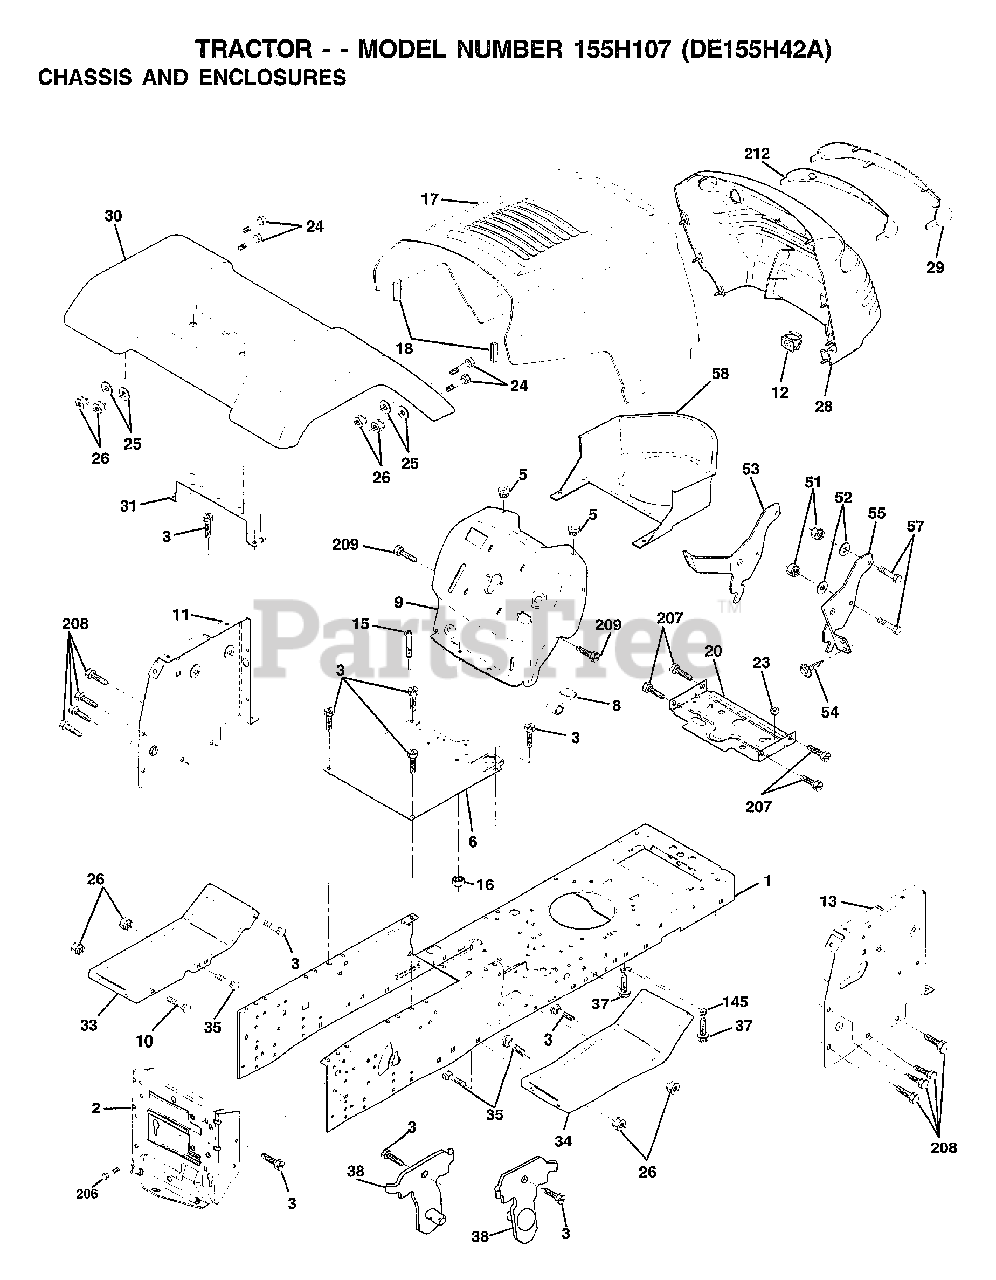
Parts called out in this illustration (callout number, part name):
2	DRAWBAR
3	SCREW
5	BUMPER-HOOD/DASH
6	SADDLE
8	CLIP.RETAINER
9	DASH
11	"PANEL-DASH,LH"
12	CLIP.TINNERMAN
15	SCREW
20	"PLATE-MTG,BATT/FU"
24	BOLT
25	WASHER
26	NUT
31	BRKT FENDER
33	FOOTREST
35	BOLT
37	SCREW LT
38	BRKT ASM PIVOT MOWER REAR
51	NUT
52	WASHER
53	BRACKET.GRILLE.LH
54	SCREW.HEX.WS.HD
55	BRACKET.GRILLE.RH
58	AIR DUCT
145	"ROD POVOT,CHASSIS"
206	BOLT SHOULDER
207	SCREW
208	SCREW
209	SCREW
212	INSERT LENS REFLECT
